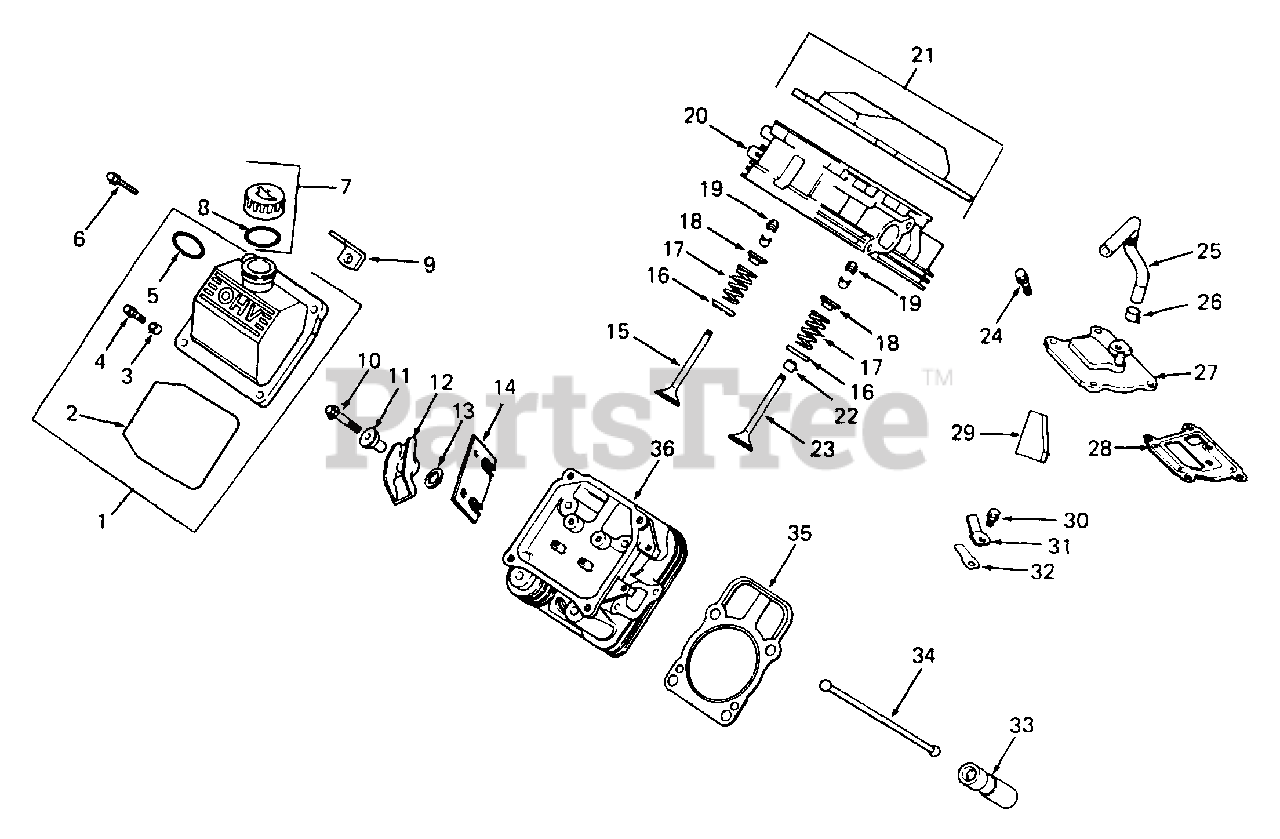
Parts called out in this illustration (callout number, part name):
1	Kit, Valve Cover Oil Fill
2	O-Ring
4	Screw, M6 x 1.0 x 30
5	O-Ring
6	Screw, M10 x 1.5 x 91
7	Kit, Oil Fill Cap
8	O-Ring, Oil Fill Cap
9	Strap, Lifting
10	Screw, M6 x 1.0 x 34
11	Pivot, Rocker Arm
13	Washer, Flat
14	Plate, Guide
15	Valve, Exhaust, Std
16	Retainer, Spring
17	Spring, Valve
18	Cap, Valve Spring
19	Kit, Retainer
20	Head Assy, Cylinder #1
21	Kit, Valve Cover, Plain
22	Seal, Valve Stem
23	Valve, Intake, Std
24	Screw, M6 x 1.0 x 20
25	Hose, Breather
26	Clamp, Breather
27	Kit, Breather
28	Gasket, Breather
29	Filter, Breather
30	Screw, Breather Reed Retainer, M5 x 0.8 x 10
31	Retainer, Breather Reed
32	Reed, Breather
33	Lifter, Valve
34	Rod, Push
35	Gasket, Cylinder Head
36	Head Assy, Cylinder #2
